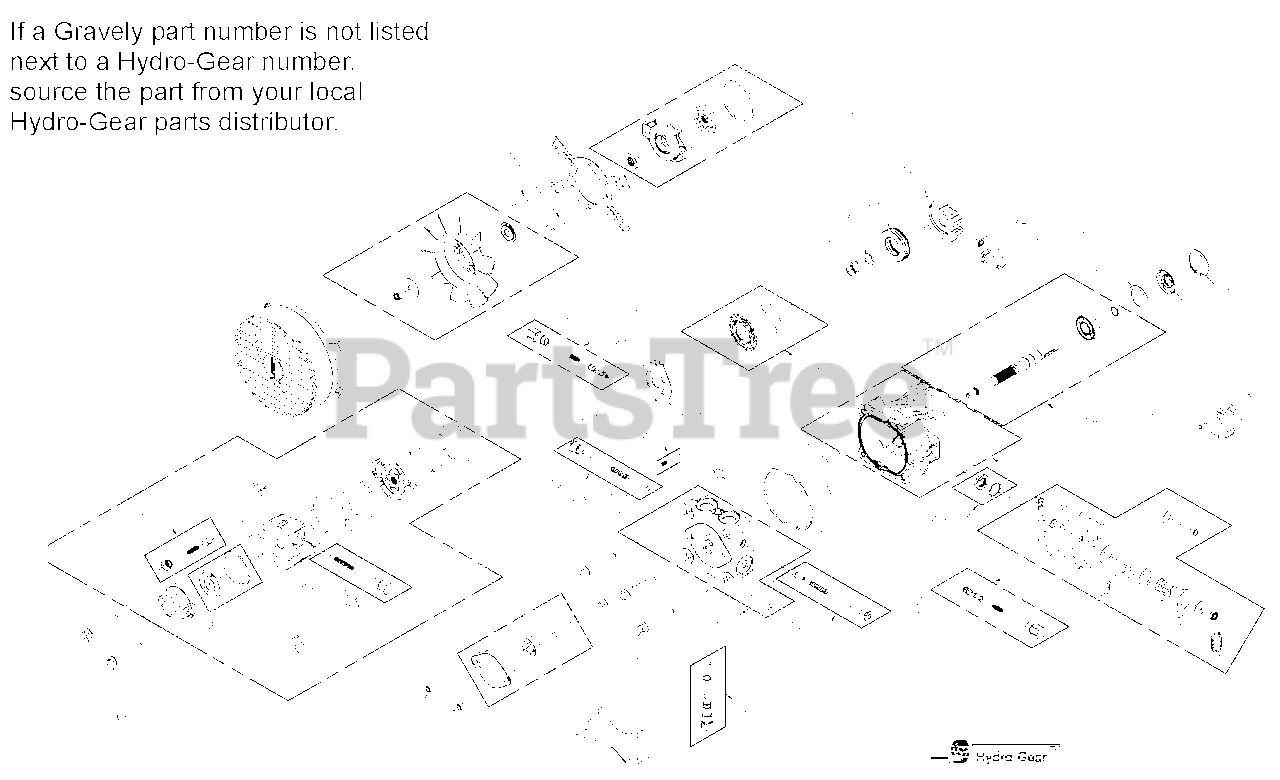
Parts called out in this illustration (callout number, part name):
1	Kit, Housing
2	Kit, End Cap W/PPT & STD
3	Pin, .219 x 1
4	Hex, Flange Bolt M8-1.25 x 60mm
5	Kit, Chg Pump
10	Screw, Cap M6 x 1 x 25
15	Kit, Bypass Valve
18	Kit, Pump Shaft 15mm Keyw
20	Seal, Lip 17 x 40 x 7
21	Washer 1.23 x 1.56 x .04
22	Ring, Ret 1.56 Int
25	Kit, 10 CC Block
29	Spring, Block
30	Washer, Thrust .59 x .78 x .04
31	Plate, Valve
32	Swashplate 10cc
34	Bearing, Thrust Ball 30 x 52 x 13
37	Arm, Trunnion 10 Cc
38	Guide, Slot
42	Kit, Shock Valve 200 Bar
44	Kit, Chg Relief
49	Kit, BDP-10l Seal
56	Plug 7/16-20 (Metal)
NS	Kit, Overhaul Seal
